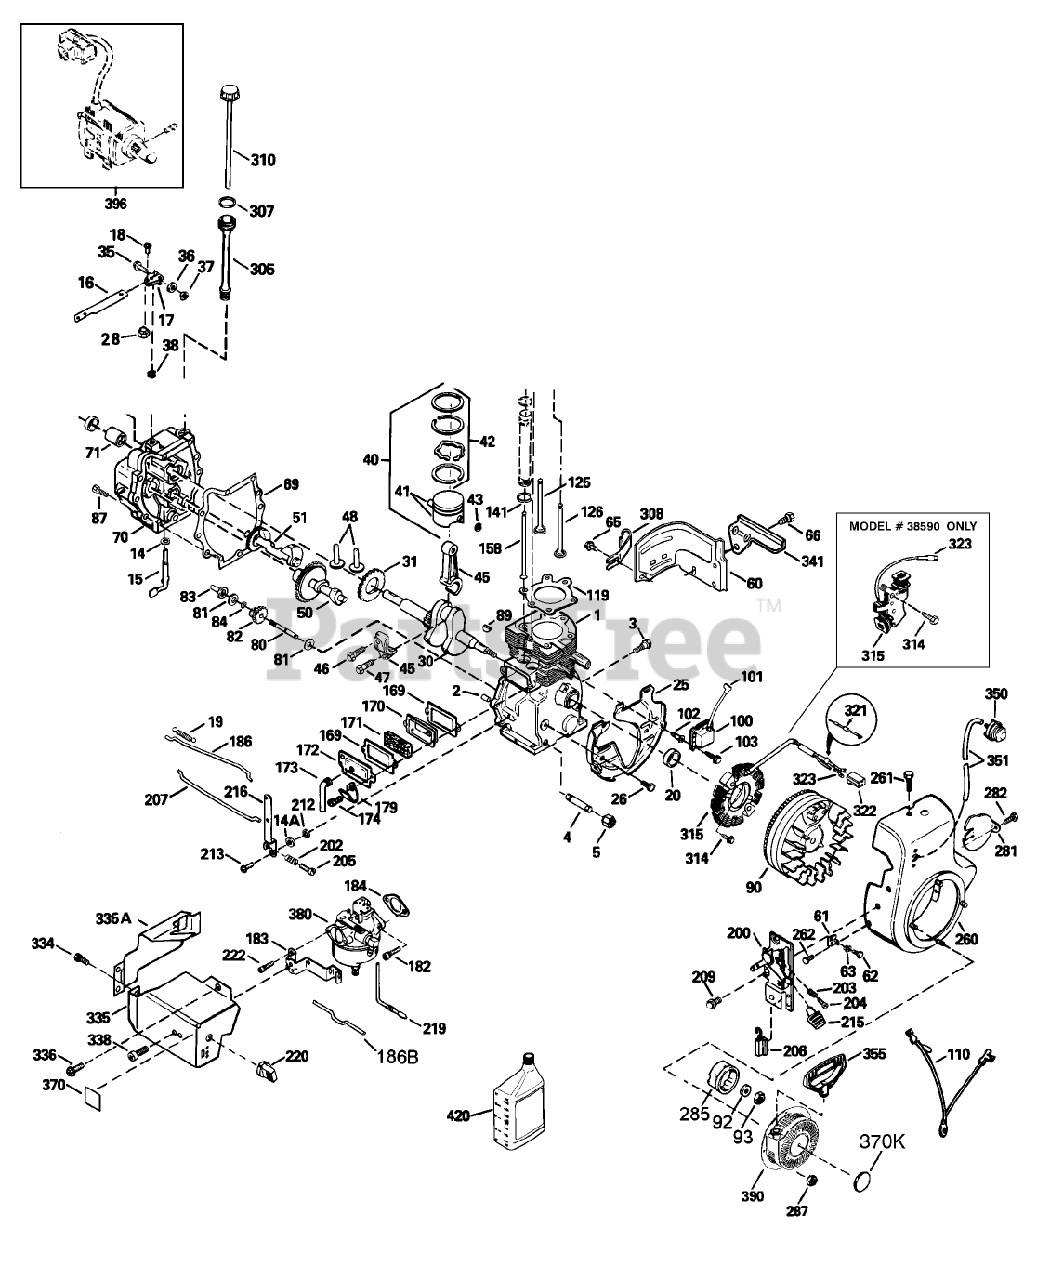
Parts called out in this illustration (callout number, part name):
1	Cylinder (Incl. Ref.#2, 20, 72 80)
2	Pin-Dowel
3	Screw (1/4-20x1/2)
5	Cap-Pipe
14	Washer-Flat
14A	Washer
15	Governor Rod (Incl. Ref.#14 38)
16	Governor Lever
17	Clamp-Lever, Governor
18	Screw
19	Throttle Spring
20	Seal-Oil
25	Baffle-Housing, Blower
26	Screw (1/4-20x19/32)
28	Nut-Lock
30	Crankshaft
31	Counterbalance Gear
35	Screw
36	Washer-Lock
37	Nut-Lock
38	Ring-Retaining
40	Piston, Pin Ring Assy. Std.(Includes ref. #41, 42 43)
40	Piston, Pin Ring Assy. .010 oversize(Includes ref. #41, 42 43)
40	55079/55080 PLYMOUT
41	Piston Pin Assembly Standard (Includes ref. #43)
41	Piston Pin Assembly .010 oversize (Incl. ref. #43)
41	Piston Pin Assembly .020 oversize (Incl. ref. #43)
42	Ring Set (STD)
42	Ring Set (.010)
42	Ring Set (.020)
43	Retaining Ring-Piston Pin
45	Rod Assembly-Connecting (Incl. ref. #46, 47 49)
46	Bolt-Rod
47	Bolt-Rod
48	Lifter-Valve
50	Camshaft
51	Counterbalance Weight
60	Extension-Housing, Blower
61	Bracket
62	Screw (8-32 x 3/8)
63	Grommet
65	Screw
66	Screw (1/4-20x19/32)
69	55072/75/86/89 TWO
70	Cylinder Cover (Incl. Ref. #14, 15, 38, 71, 75)
71	2025A77 WIZARD ROTA
75	Seal-Oil
80	Governor Shaft
81	Washer
82	Gear-Asm Governor
83	Governor Spool
84	Ring-Retaining
86	Screw (1/4-20x1-3/16)
87	Screw (1/4-20x1-11/16)
89	Key-Flywheel
90	Flywheel (W/Ring Gear)
90	Flywheel ASM
92	Washer-Belleville
93	Nut-Flywheel
100	Solid State ASM
101	Cover-Spark Plug
103	Screw (T-15, 10-24 x 15/16)
110	Ground Wire
119	Cylinder Head Gasket
125	Exhaust Valve (Std.)
125	Exhaust Valve (1/32)
126	Intake Valve (Std.)
126	Intake Valve (1/32)
158	Rod-Push
169	Gasket-Cover, Valve
170	Body-Breather
171	Element-Breather
172	Cover-Valve
173	Tube-Breather
174	Screw
179	Retainer Clip
182	Screw (T-30, 1/4-20 X 27-32)
183	Bracket-Choke
184	Gasket-Carburetor To Intake Pipe
186	Governor Link
186B	Spring-Choke
200	Bracket-Control (Incl. Ref. #203, 204 and 206)
202	Compression Spring
203	Spring-Compression
204	Screw
205	Screw
206	Terminal
207	Choke Link
209	Screw (10-32 x 1/2)
212	Bushing
213	Screw
215	Knob-Control
216	Lever-Adjusting
219	Rod-Choke
220	Knob-Control
222	Screw (10-32 x 1/2)
260	Blower Housing
261	Screw
262	Screw
281	Screw
282	Screw (8-32 x 3/8)
285	Cup-Starter
287	Nut and Lock Washer (1/4-28)
305	Tube-Fill, Oil
307	O-Ring
308	Clip-Tube, Fill
310	Dipstick
314	Screw (1/4-20 x 3/4)
315	Alternator Coil (3/5)(Incl. 321-323)
315	Coil-Alternator, 18 Watt (Includes 323)
321	Diode
322	Body-Connector
323	Terminal
334	Screw (8-32 X 5/16)
335	Carburetor Cover
335A	Carburetor Cover
336	Screw (10-32x1/2)
338	Screw (10-32 x 1/2)
341	Bracket-Fuel Tank
350	Primer-Asm
351	Line-Primer
355	Handle-Starter, Mitten Grip
370	Decal-Lubrication
370K	Decal-Tecumseh Logo for Top of Recoil Starter
380	Carburetor (Incl. Ref. #184)
390	Starter-Rewind
396	Starter-Electric (110 Volt)
420	Oil-Engine (SAE 5W30)
